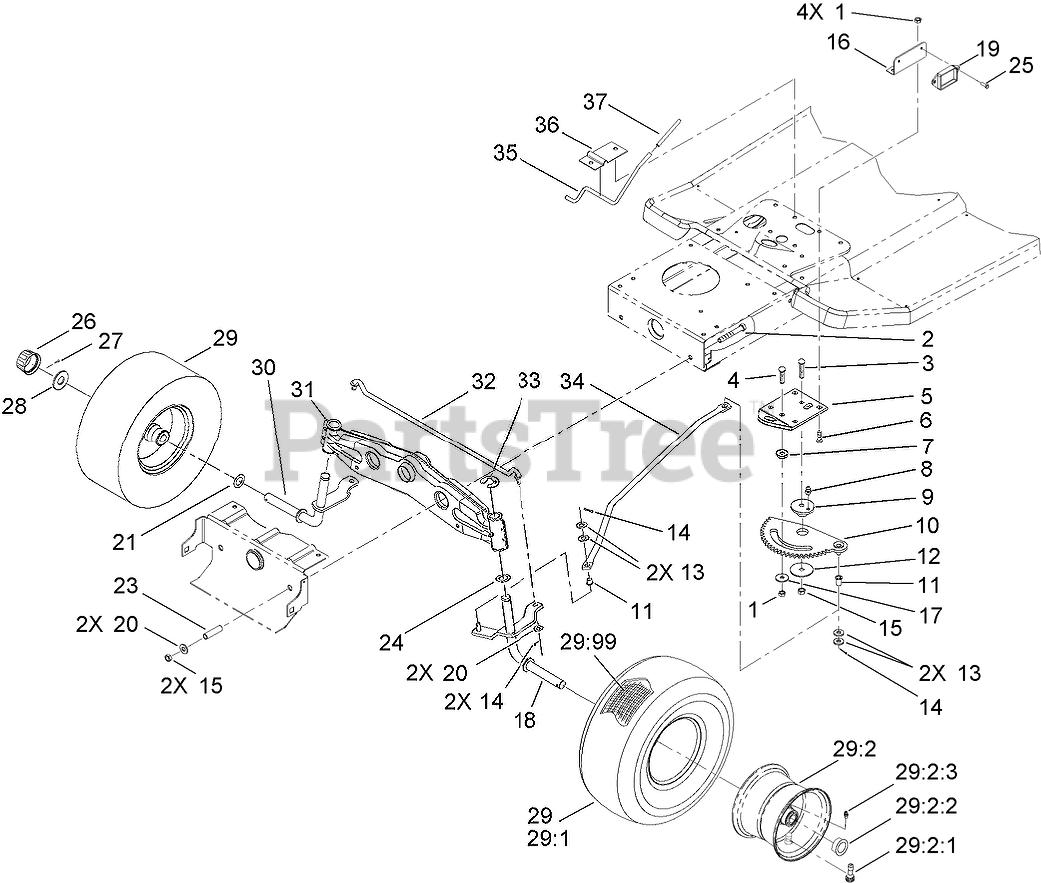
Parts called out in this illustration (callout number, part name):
1	NUT-LOCK, NI
2	SCREW-HH
3	SCREW-CARR
4	SCREW-CARR
5	BRACKET-RACK, STEERING
6	BOLT-CARR
7	SPACER-RACK, STEERING
8	FITTING-GREASE
9	BUSHING-ECCENTRIC
10	RACK-STEERING
11	BUSHING-FLANGED, NYLON
12	WASHER-BEARING
13	WASHER-FLAT
14	PIN-COTTER
15	NUT-LOCK, NI
16	BRACKET-MODULE
17	WASHER-PIVOT
18	LH SPINDLE ASM
19	MODULE
20	WASHER-FLAT
21	WASHER-THRUST
23	SPACER
24	WASHER-THRUST
25	SCREW-HWH
26	CAP-HUB
27	PIN-COTTER
28	WASHER-PLAIN
29	FRONT WHEEL and TIRE ASM
29:2	RIM ASM
29:2:1	STEM-VALVE
29:2:2	BEARING-WHEEL
29:2:3	FITTING-GREASE
30	RH SPINDLE ASM
31	FRONT AXLE ASM
32	TIE ROD-STEERING
33	E-RING
34	LINK-DRAG
35	ROD-BRAKE, PARKING
36	BRACKET-PARKING BRAKE
37	GRIP-BRAKE, PARKING
